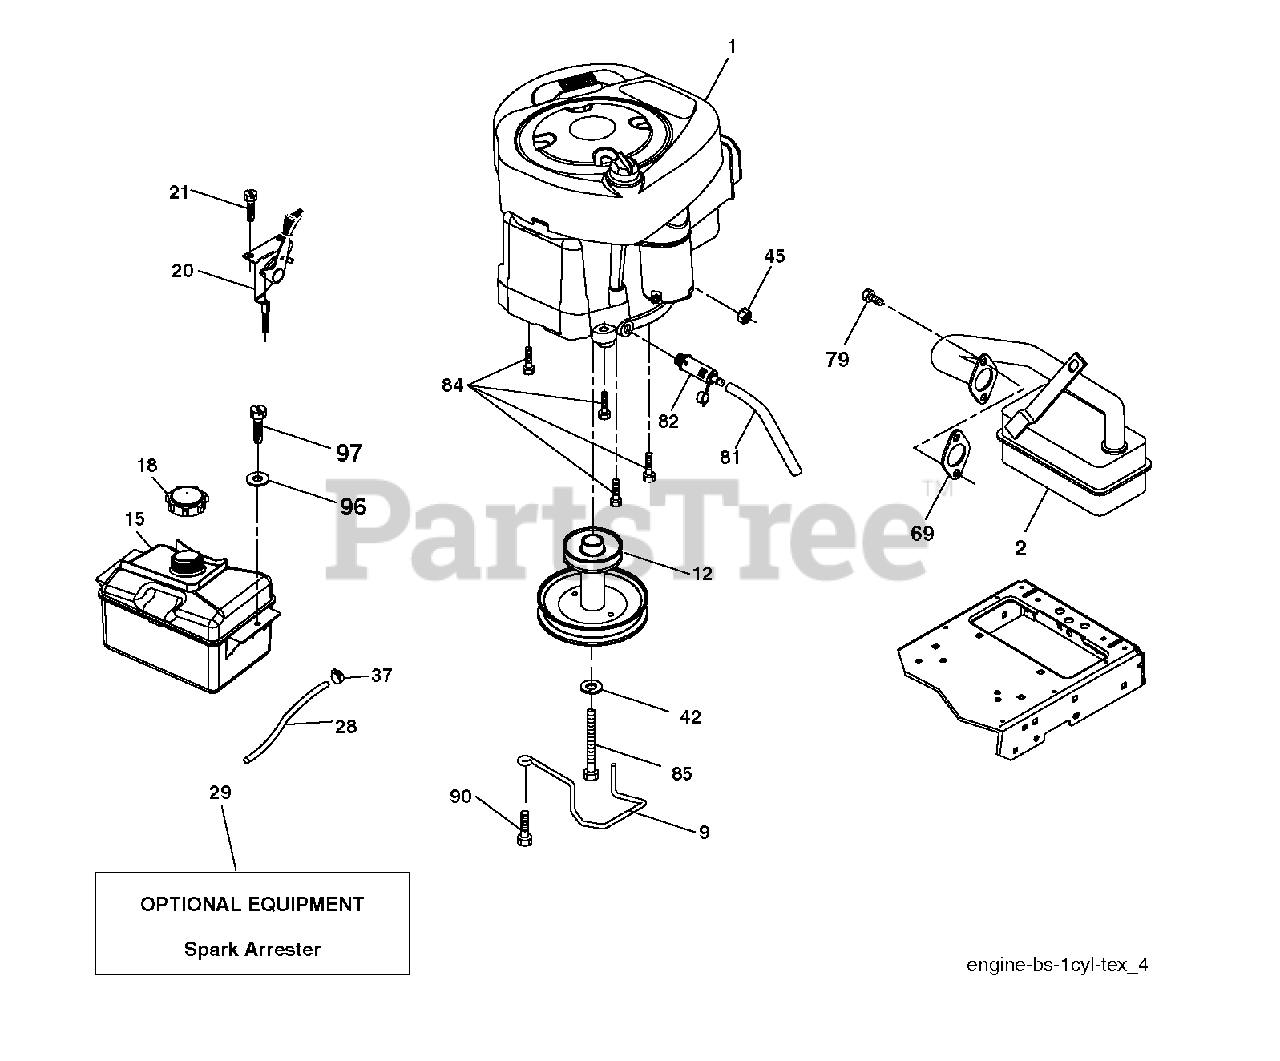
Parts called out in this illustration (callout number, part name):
9	KEEPER.BELT.ENGINE.3.25
12	PULLEY ENGINE
15	TANK FUEL FRT 1.5 GAL
18	FUEL CAP
20	CONTROL.TH/CK.C.
21	SCREW
28	LINE.FUEL.20
29	ARRESTER SPARK (OPTIONAL)
37	HOSE CLAMP
42	LOCKWASHER
45	NUT
69	REPL BY 532 27 22-93
79	SCREW.SOCKET HD.5/16-1
81	TUBE, DRAIN OIL ASM.
82	PLUG DRAIN OIL EASY
84	SCREW.3/8-16
85	BOLT HEX 7/16-20X4-1/4"
90	SCREW 3/8-16X1
